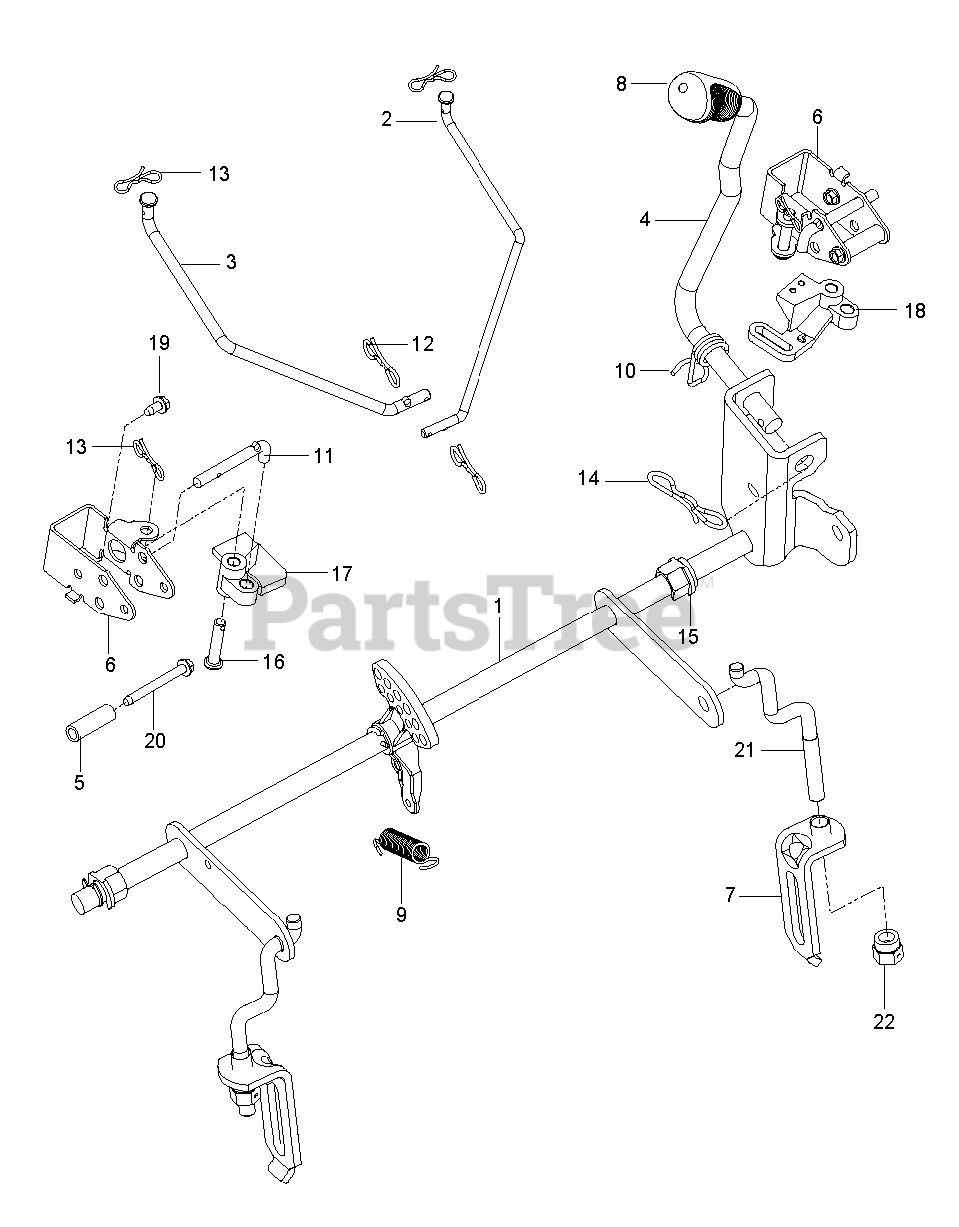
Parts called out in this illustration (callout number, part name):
1	SHAFT ASSY DECK LIFT WELDMENT
2	LINK.BRAKE.PARK.UPPER.LH
3	LINK.BRAKE.PARK.UPPER.RH
4	HANDLE LIFT ZTR
5	SPACER.334.ID.5.OD.1.5.L
6	BRACKET.BELLCRANK.PBRAKE X431
7	ASSEMBLY, BRKT LINK
8	GRIP.HANDLE.LIFT.PVC.BLACK
9	RETURN.BRAKE.PARK.AUTO
10	SPRING.TORSION.LIFT.HANDLE
11	ROD.PUSH.BRAKE
12	PIN COTTER;LOCKING;BOWTIE;1IN
13	PIN.COTTER.7/16.BOW TI.
14	PIN.COTTER.5/16.BOW TI
15	PLASTIC NUT
16	PIN.5.16X1.5
17	BELLCRANK.RH
18	BELLCRANK.LH
19	SCREW.1/4-20X5/8
20	SCREW THD;ROLL;1/4-20 X 2.25
21	LINK, REAR SUSPENSION
22	NUT, LIFT LINK 7/16-20
